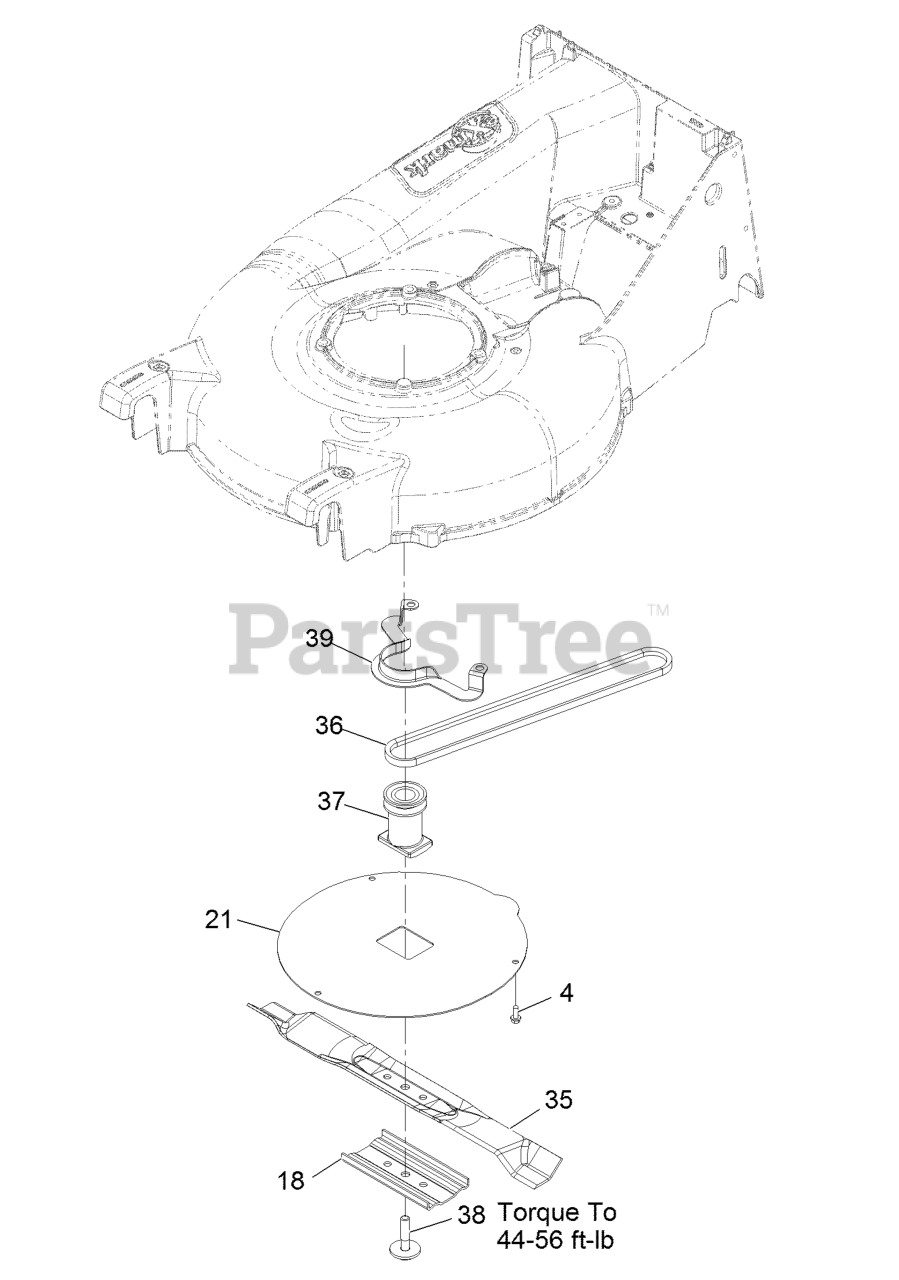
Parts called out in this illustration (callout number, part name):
4	SCREW-HWH
18	SUPPORT-BLADE
36	BELT,3L P21 DRIVE
37	BLADE-ADAPTER
38	BOLT-BLADE, SEM
39	GUIDE-BELT
